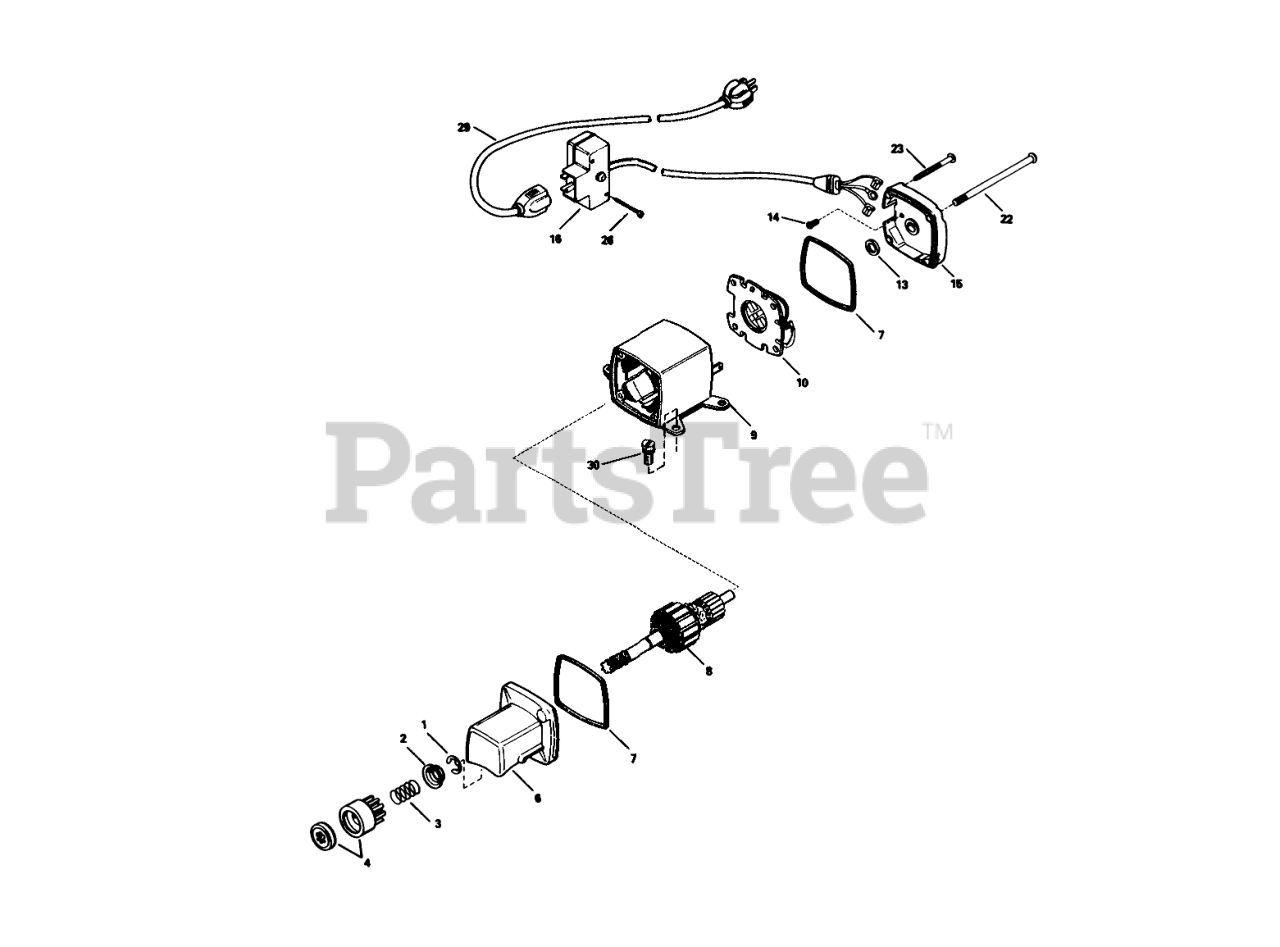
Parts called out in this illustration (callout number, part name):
1	Retainer-Ring
2	Retainer-Spring
3	Spring-Anti Drift
4	Nut & Gear
6	Cap Assy.-Drive End (Incl. Ref. #7)
8	Armature
9	Housing Assembly
10	Card ASM
13	Washer-Thrust
14	Screw-Ground
15	Cap Assy.-Commutator End (Incl. Ref. #7)
16	Switch Box ASM
22	Bolt-Case
23	Screw-Ground
29	Cord-Extension
30	Screw (T-30, 1/4-20 x 23/32)
